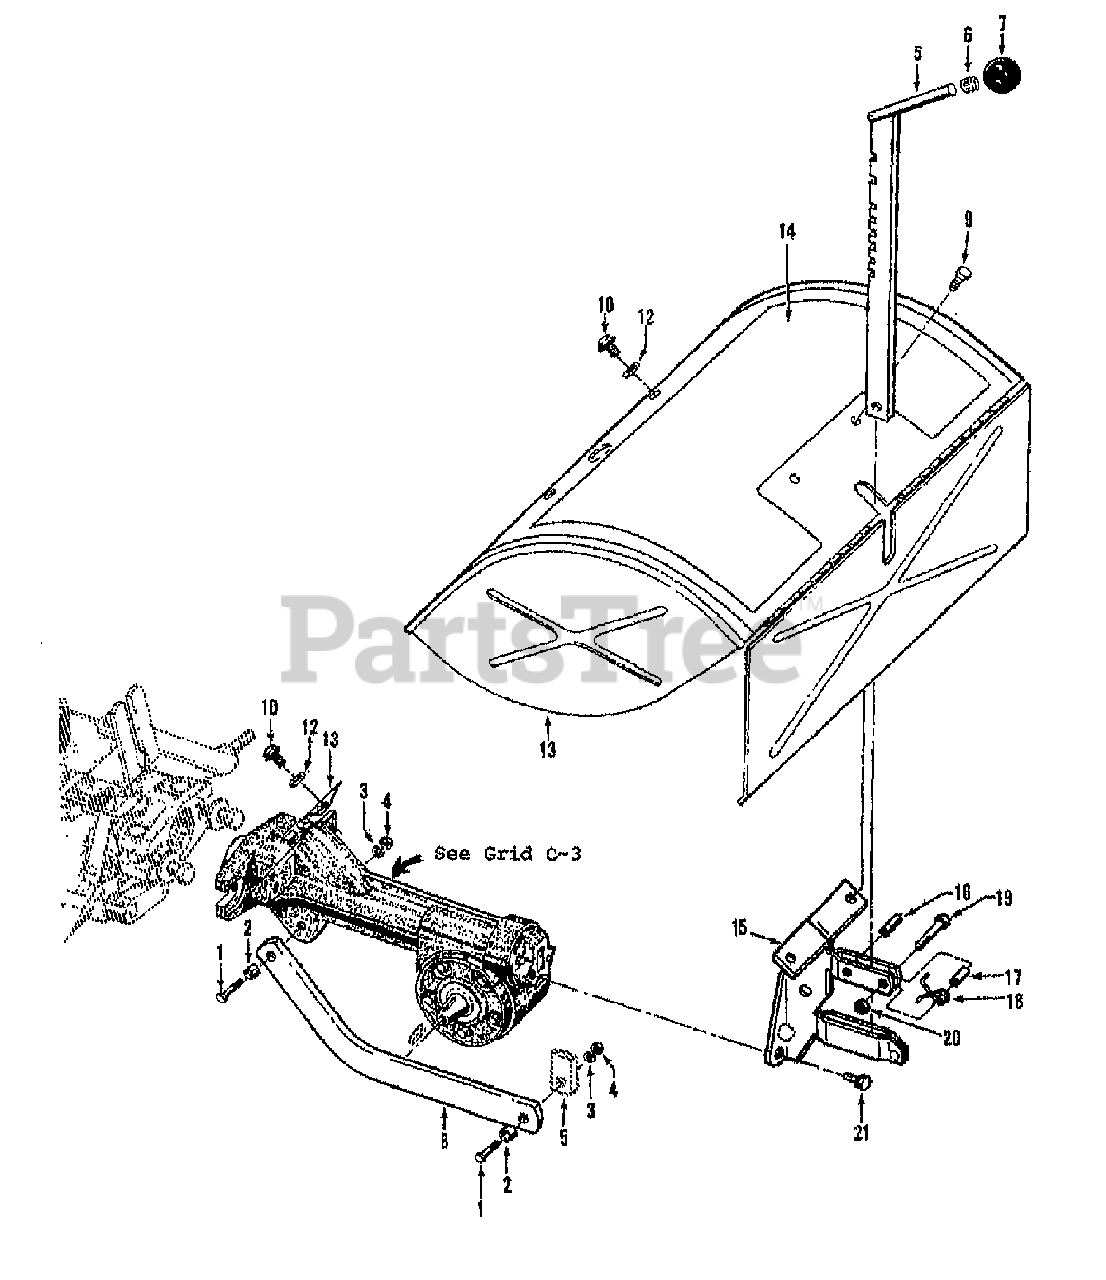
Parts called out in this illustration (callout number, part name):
1	SCR-HH 3/8-16X1.25
2	BUSHING-.5X.375X.3
3	WASHER-LK .375 @ DEPL
4	NUT-HEX 3/8-16 ZP
5	DEPTH REGULATOR W/KNOB
6	RING-TOLERANCE .5325 ID
7	KNOB-CONTROL
8	BAR-DRAG RED
9	SCR-HWH 1/4-20 X .5 STH
10	SCR-HFLK 5/16-18X.75 ZP
11	THIS REF. NO. NOT USED
12	WASHER-#1.125X.344 ZP
13	HOOD W/DECALS OPC SERVICE
14	DECAL-HOOD INST
15	BRKT W/ROLL PIN (9308)
16	PIN-ROLL .25 X 1
17	SPACER-.250X.343X.375
18	SPRING-TORSION
19	SCR-HH 1/4-20X1.0
20	NUT-LK 1/4-20
21	SCR-HFLK 5/16-18X.62 G5ZP
